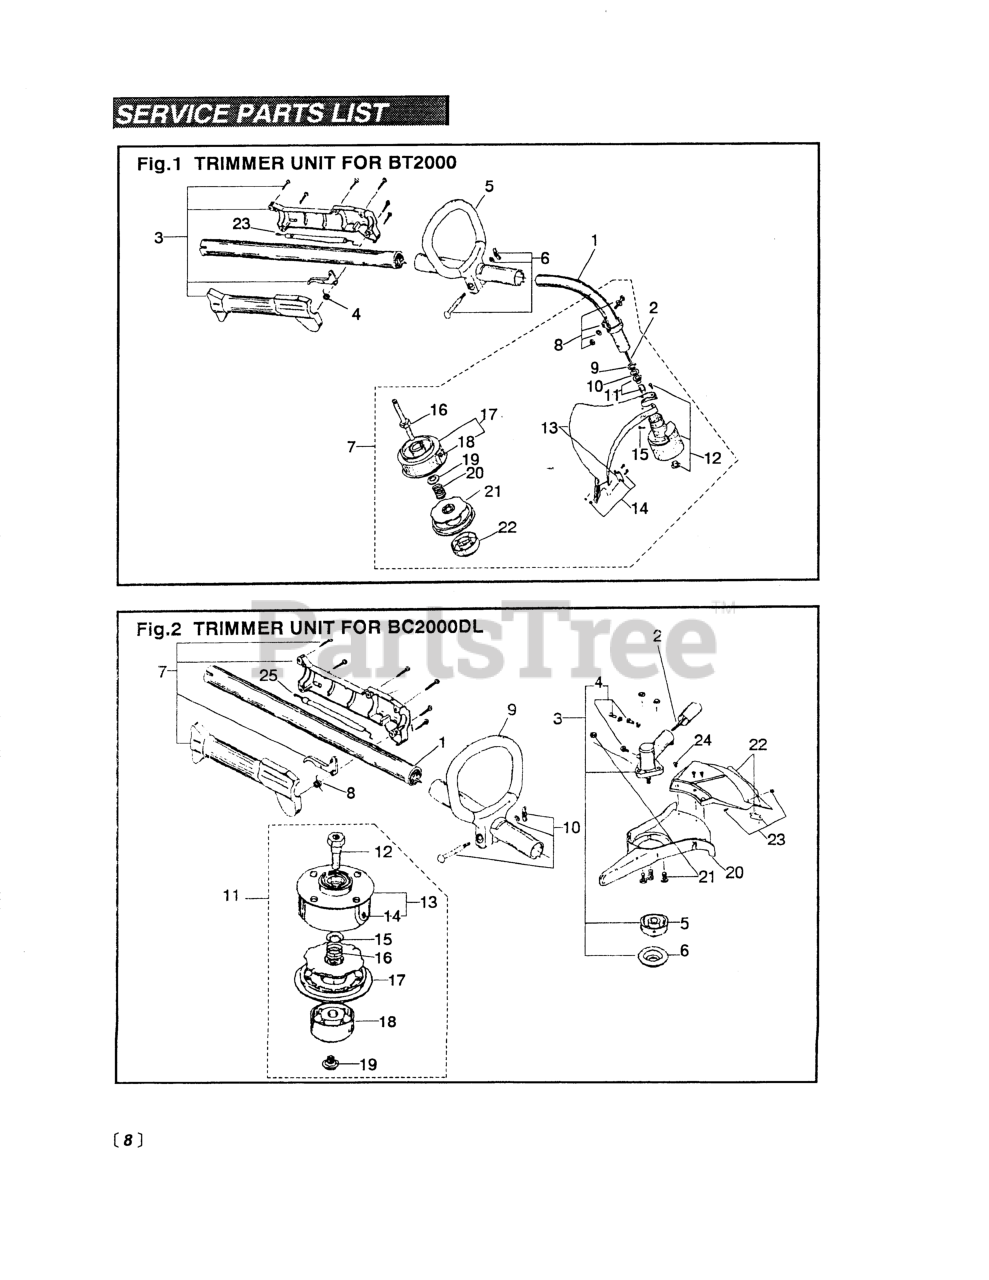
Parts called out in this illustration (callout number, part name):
1	SHAFT ASSEMBLY (BT)
4	SPRING, THROTTLE TRIGGER
7	CUTTING HEAD ASSEMBLY
8	CLAMP ASSY, LOWER
9	RING, RETAINING
10	WASHER
11	ASSY, BUSHING HOUSING
12	SCREW, GUARD MTG (SET)
14	BLADE ASSEMBLY
15	SET SCREW, ANTI-ROTATION
17	OUTER SPOOL ASSEMBLY
18	EYELET
19	WASHER, EYELET
